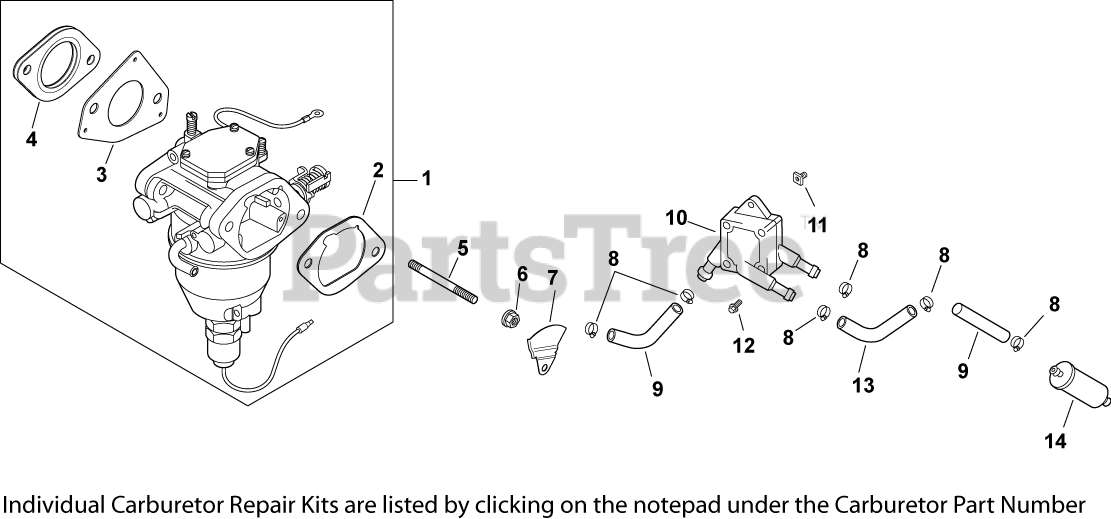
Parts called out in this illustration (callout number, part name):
1	CARBURETOR KIT-USE 24 853 169-S
2	GASKET, AIR CLEANER BASE
3	GASKET, CARBURETOR
4	GASKET, CARBURETOR
5	STUD,M6X1.0X96
6	NUT, FLG M6X1.0
7	BAFFLE, SPIT-BACK CUP-USE 24 063 105-S
8	CLAMP, HOSE (KM)-USE 25 237 31-S
9	HOSE,LW PERM.FUEL 24.00"-USE 25 111 81-S
10	PUMP, FUEL
11	NUT, PLASTIC - BLACK
12	SCREW, TAP M6X1.7X18
13	LINE, FUEL 11"
14	FILTER, FUEL
